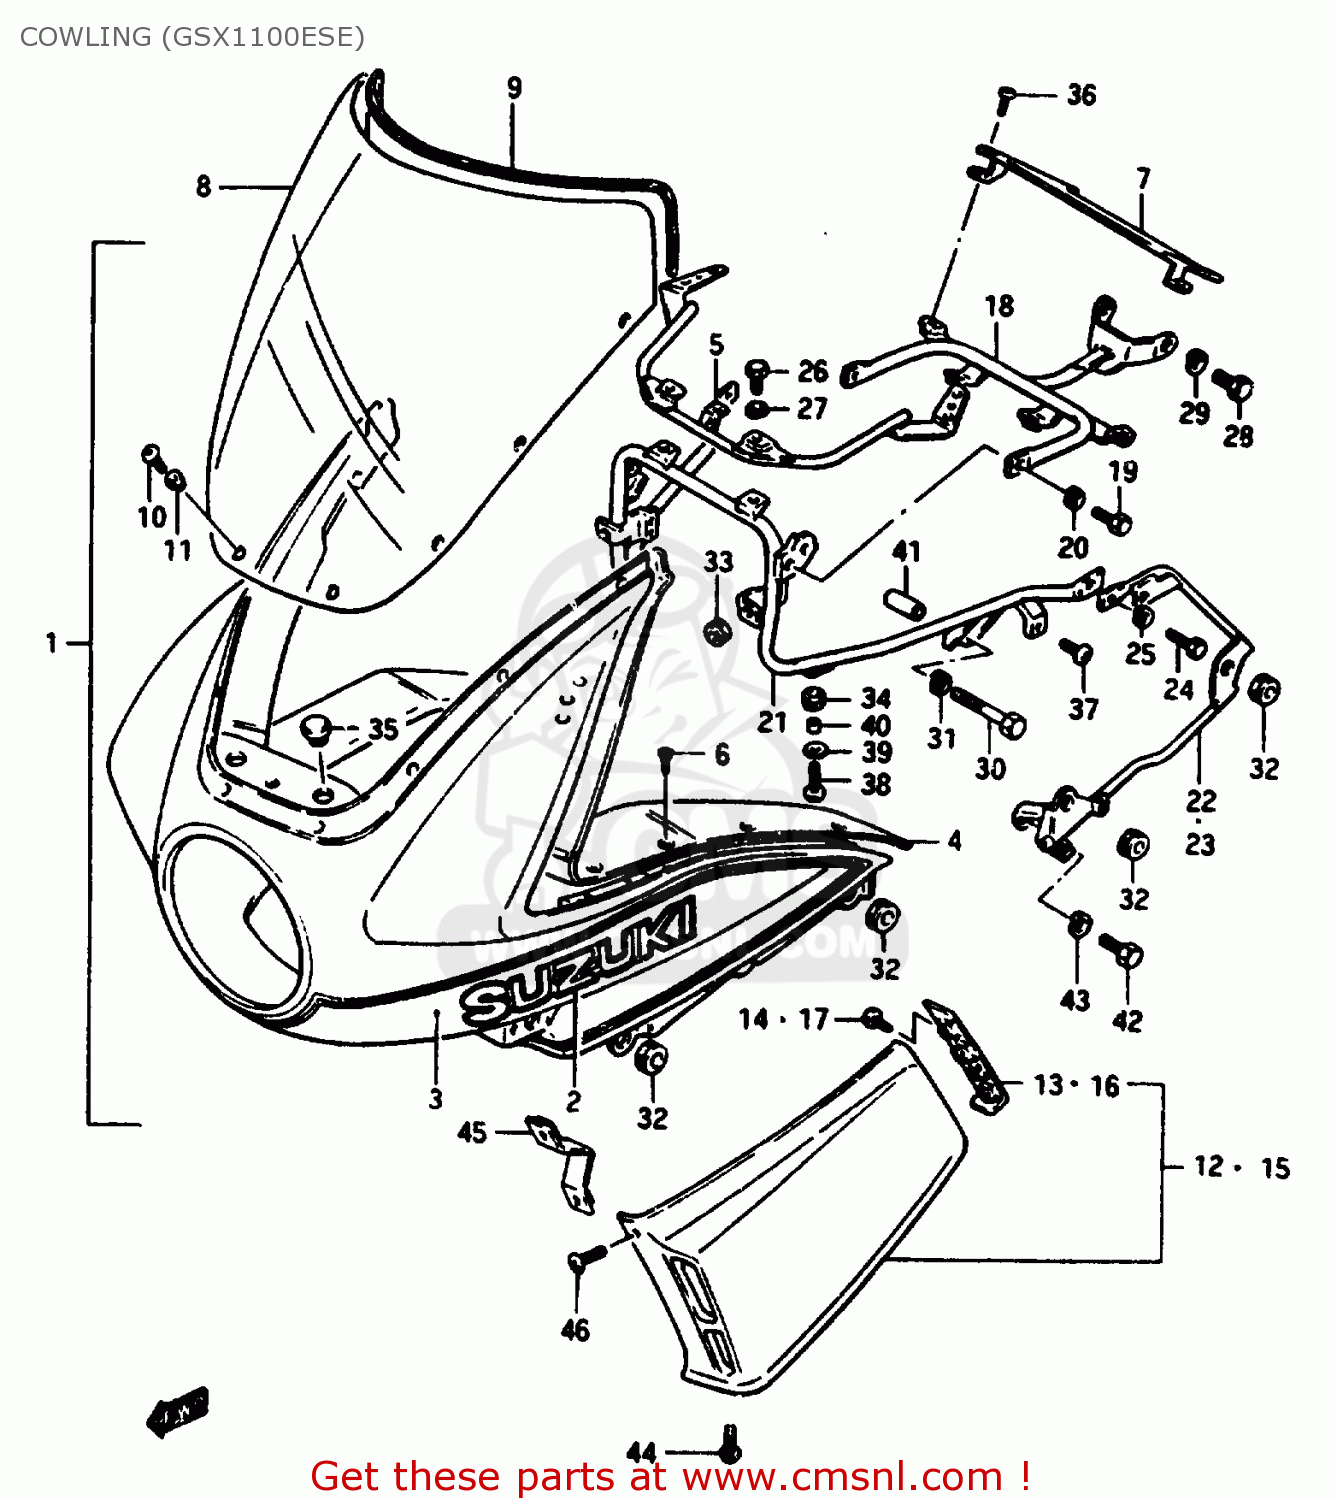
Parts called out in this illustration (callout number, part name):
1	COWLING ASSY
2	EMBLEM
3	TAPE SET
4	PANEL,COWLING
5	BRACE,COWLING BODY
6	SCREW, PANEL
7	COVER,METER,REAR
8	SCREEN
9	MOLDING
10	SCREW(5X20)
11	CUSHION
12	COVER,COWLING
13	PANEL,COWL SIDE COVER RR RH
14	SCREW
15	COVER, LH (WHITE)
16	PANEL,COWLING SIDE COVER
17	SCREW
18	BRACE,COWLING,FRONT
19	BOLT
20	LOCK WASHER
21	BRACE,COWL RR
22	BRACE,COWLING SIDE,RIGHT
23	BRACE,COWLING SIDE,LEFT
24	BOLT 6X16
25	LOCK WASHER
26	BOLT
27	LOCK WASHER
28	BOLT
29	LOCK WASHER
30	BOLT
31	LOCK WASHER
32	CUSHION
33	CUSHION
34	CUSHION
35	PLUG(OD:22)
36	SCREW
37	SCREW 6X12
38	SCREW, CENTER
39	WASHER(6.5X18X1)
40	SPACER (6.1X9X9)
41	SPACER (8.6X13.8X35)
42	BOLT
43	LOCK WASHER
44	SCREW
45	BRACE,SIDE,FRONT
46	SCREW
